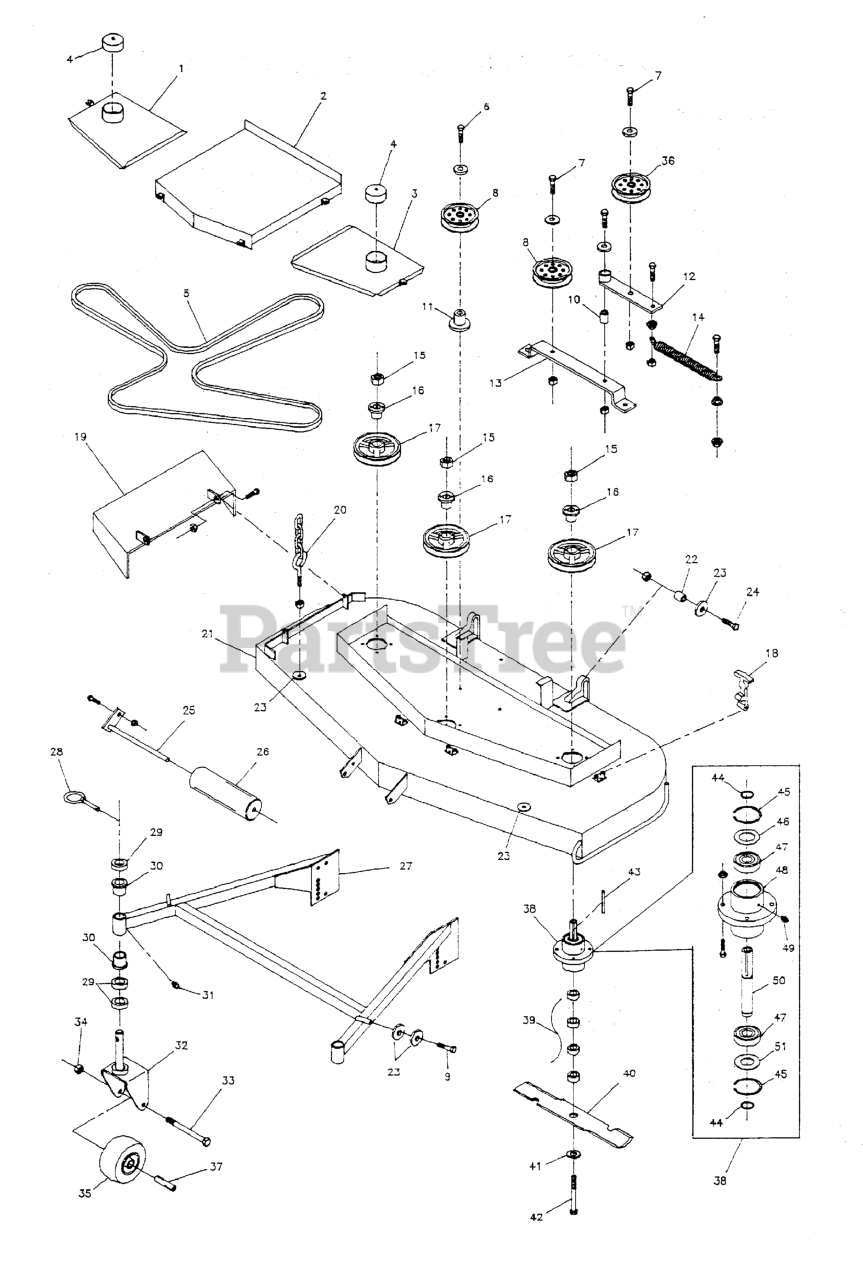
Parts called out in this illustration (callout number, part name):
1	WELD, 72" GUARD - RH
2	CENTER DECK GUARD
3	SPINDLE COVER-LH
4	VINYL CAP
5	BELT, 5V, 197.90"EL, LRG ARAMID, WRP, RC
6	BOLT, 1/2-13 x 4-1/2
7	BOLT, 1/2-20 X 2-1/2" GD5 CZ
8	PULLEY, Idler
9	BOLT, 1/2-13 X 3-1/2, HEX HD, GD5, CZ (SV)
10	SPACER, .32 x .75 x 1.06
11	SPACER, .52 X 1.00 X 1.81
12	IDLER ARM, Complete
13	IDLER MOUNT
14	SPRING, Extension
15	NUT, 5/8-11 Hex
16	BUSHING, Tapered Hub
17	PULLEY, Spindle
18	RUBBER LATCH
19	DISCHARGE CHUTE
20	DECK HANGER
21	DECK SHELL W/DECALS, P72, SIDE DISCHARGE
22	DECK MOUNT SPACER
23	WASHER, 1/2" USS
24	BOLT, 1/2-20 X 2-1/2" GD5 CZ
26	ROLLER
27	CASTER MOUNT FRAME, Complete
28	PIN, Lynch
29	SPACER, 1.02 x 1.56 x .50
30	BUSHING, FLANGE
31	GREASE FITTING
32	YOKE, Caster
33	BOLT, 1/2-13 x 5-1/2
34	NUT, 1/2-13 HEX NYLON LOCK
35	WHEEL & TIRE ASSEMBLY, White, 9 x 3.5 x 4, Complete
36	IDLER PULLEY
37	AXLE, Caster Wheel
38	SPINDLE ASSEMBLY, Complete
39	SPACER, .63 x 1.06 x .23
40	MOWER BLADE, 24-1/2"
41	WASHER, 5/8" USS
42	BOLT, 5/8-11 x 9-1/2
43	KEY, 1/4 SQ. X 2-1/2
44	SNAP RING, External
45	SNAP RING, Internal
46	SPINDLE WASHER, Top
47	BEARING
48	SPINDLE HOUSING
49	GREASE FITTING
50	SPINDLE SHAFT
51	SPINDLE WASHER, Bottom
